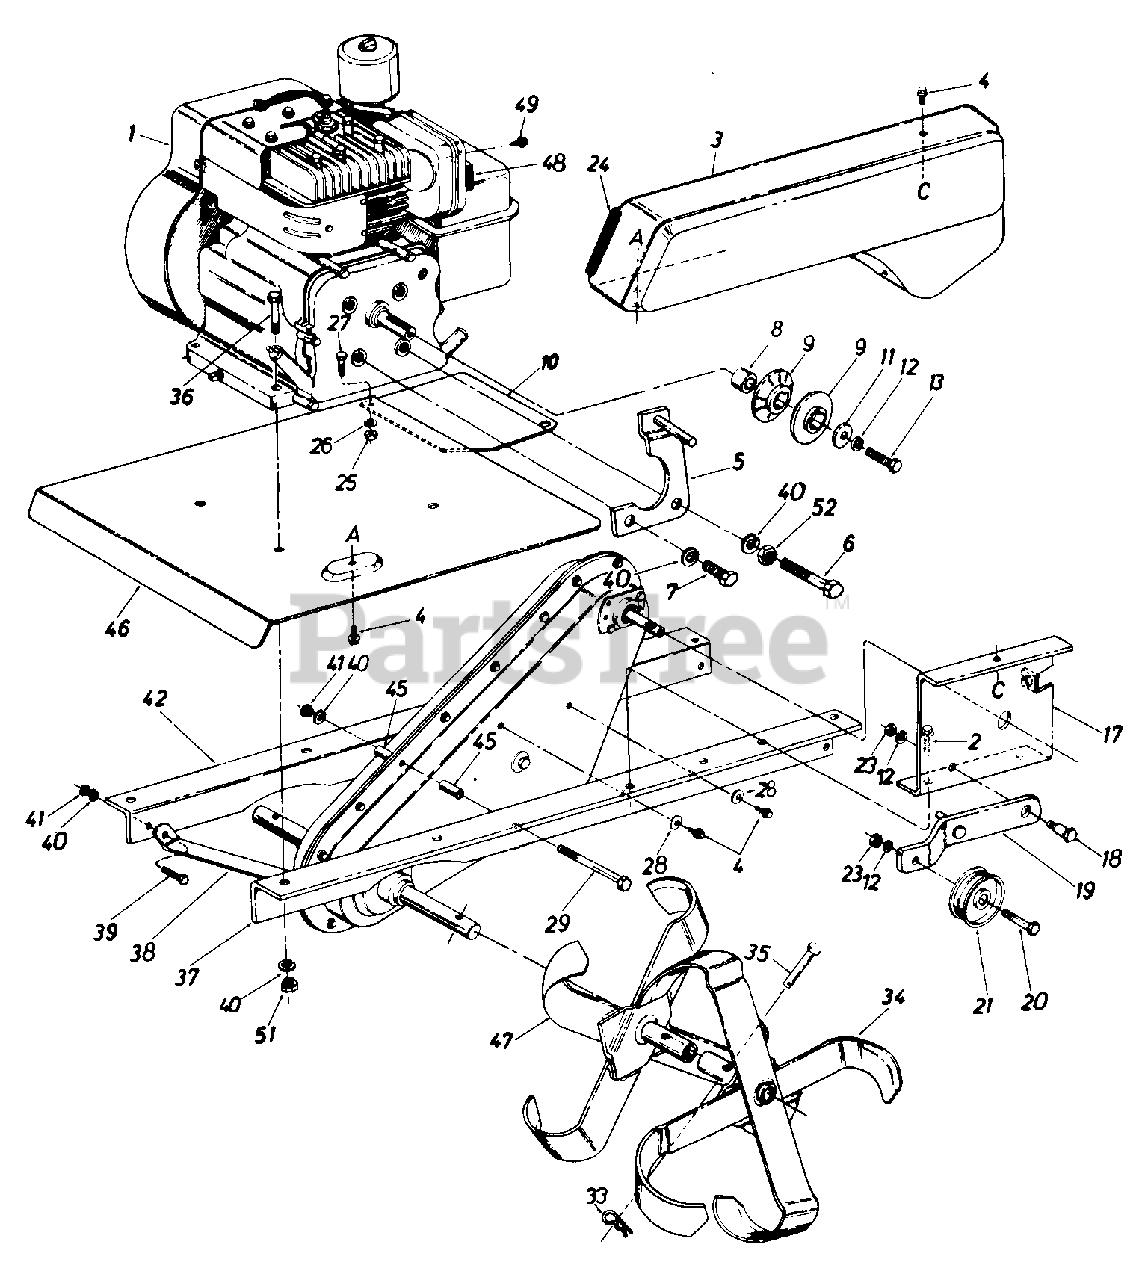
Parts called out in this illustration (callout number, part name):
1	Engine
2	Hex Self-Tap Scr. 5/16-24 x .5"
3	463 Belt Cover
4	Hex Self-Tap Scr. 1/4-20 x .5"
5	Belt Keeper Brkt. Ass'y.
6	Hex Bolt 5/16-24 x 2.25" Lg. (Gr. 5)
7	Hex Bolt 5/16-24 x .62" Lg. (Gr. 5)
10	Tine Shield Extension
11	Fl-Wash. 3/8" I.D. x 1.25"
12	L-Wash. 3/8" I.D.*
13	Hex Bolt 3/8-24 x 1.00" Lg.
17	463 Idler Mounting Brkt.
18	Shld. Bolt
19	Idler Bracket Ass'y.
20	Hex Bolt 3/8-16 x 1.5" Lg.
21	Idler Pulley
23	Hex Jam Nut 3/8-16 Thd.
24	Trim Strip-3"
25	Hex Nut 1/4-20 Thd.
26	L-Wash. 1/4" I.D.
27	Hex Bolt 1/4-20 x .62 Lg.*
28	Bell-Wash. .26 I.D. x .75 O.D.
29	Hex Bolt 5/16-18 x 3" Lg.
33	Hairpin Cotter
36	Hex Bolt 5/16-18 x 1.5" Lg.
37	463 Frame Rail-L.H.
38	Front Brace Brkt.
39	Hex Bolt 5/16-18 x .75" Lg.
40	L-Wash. 5/16" I.D.*
41	Hex Cent. L-Nut 5/16-18 Thd.
42	463 Frame Rail-R.H.
49	Hex Self-Tap Scr. #8-32 0 x.38" Lg.
51	Hex Nut 5/16-18 Thd.*
52	Hex Nut 5/16-24 Thd.*
